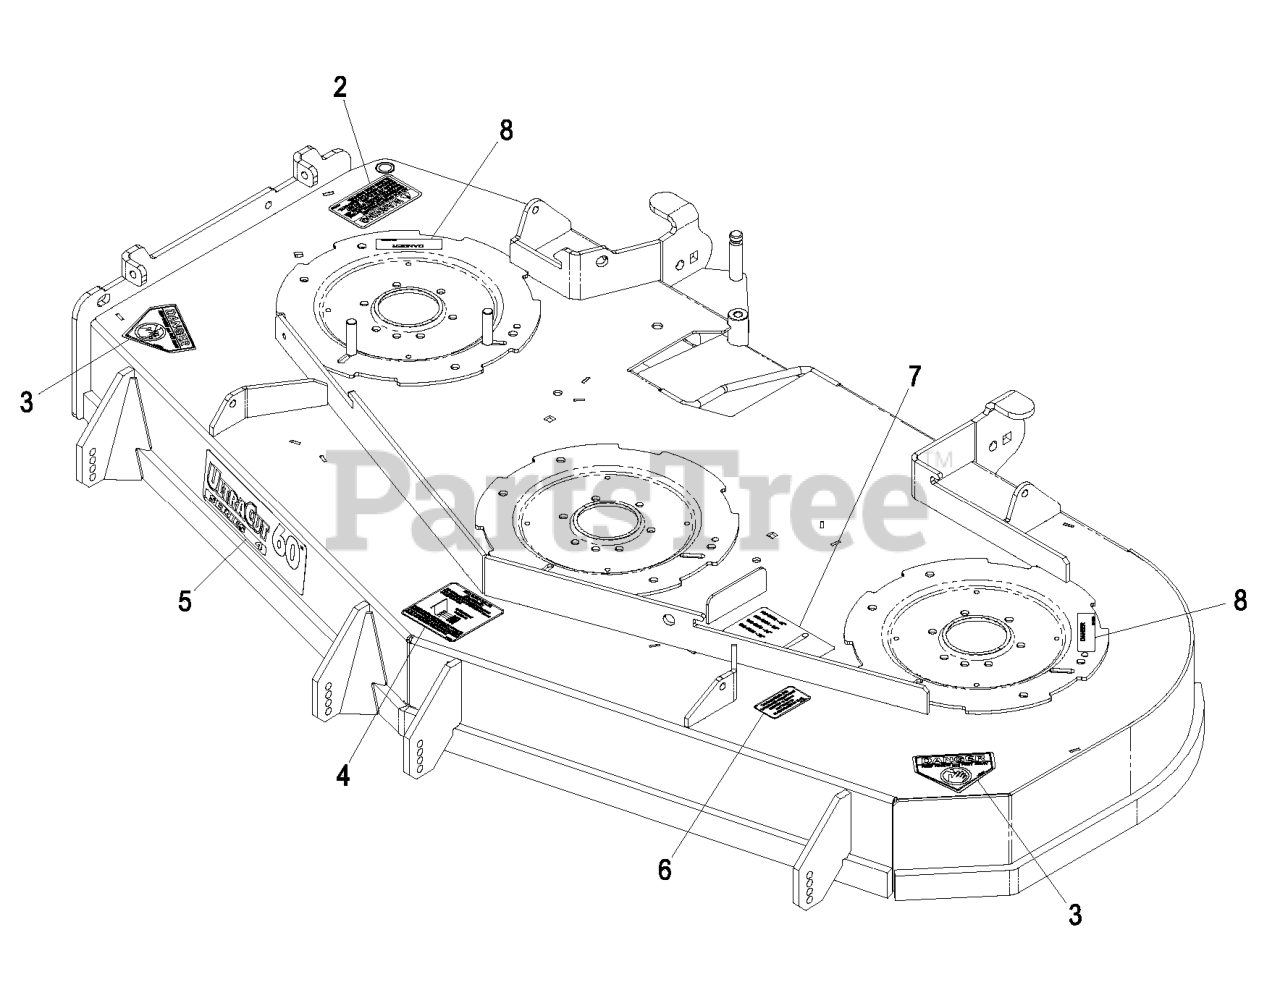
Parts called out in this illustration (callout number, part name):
2	DECAL-WARNING, DISCHARGE
3	DECAL-DANGER
4	DECAL,ANTISCALP
5	DECAL,ULTRACUT 60 SERIES
6	DECAL,BOLT TORQUE
7	DECAL,BELT ROUTING
8	DECAL-COVER, MISSING
